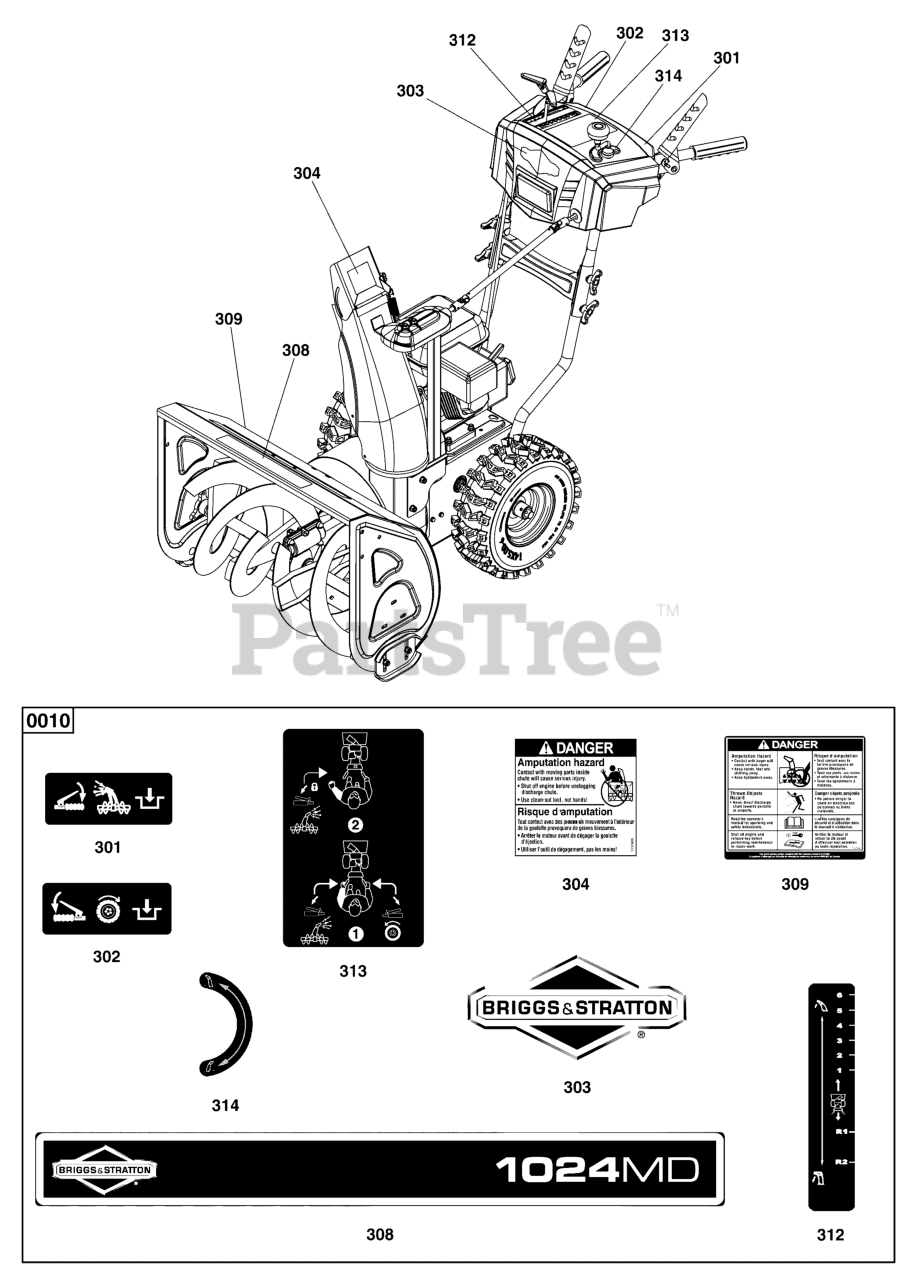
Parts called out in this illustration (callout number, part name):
1	KIT-DECAL, Briggs 1024MD
2	KIT-DECAL, Briggs 1024MD, Export
301	DECAL, Auger Control
302	DECAL, Traction Control
303	*DECAL, Control Panel, Briggs & Stratton
304	DECAL, Danger Chute Warning, FR/ENG
309	DECAL, Danger Foot, FR/ENG
312	DECAL, 1-6 Transmission Speed Control
313	DECAL, Free Hand Operation
314	DECAL, Chute Rotation
324	DECAL, Chute Warning, Export
329	DECAL, Danger Auger Icons
